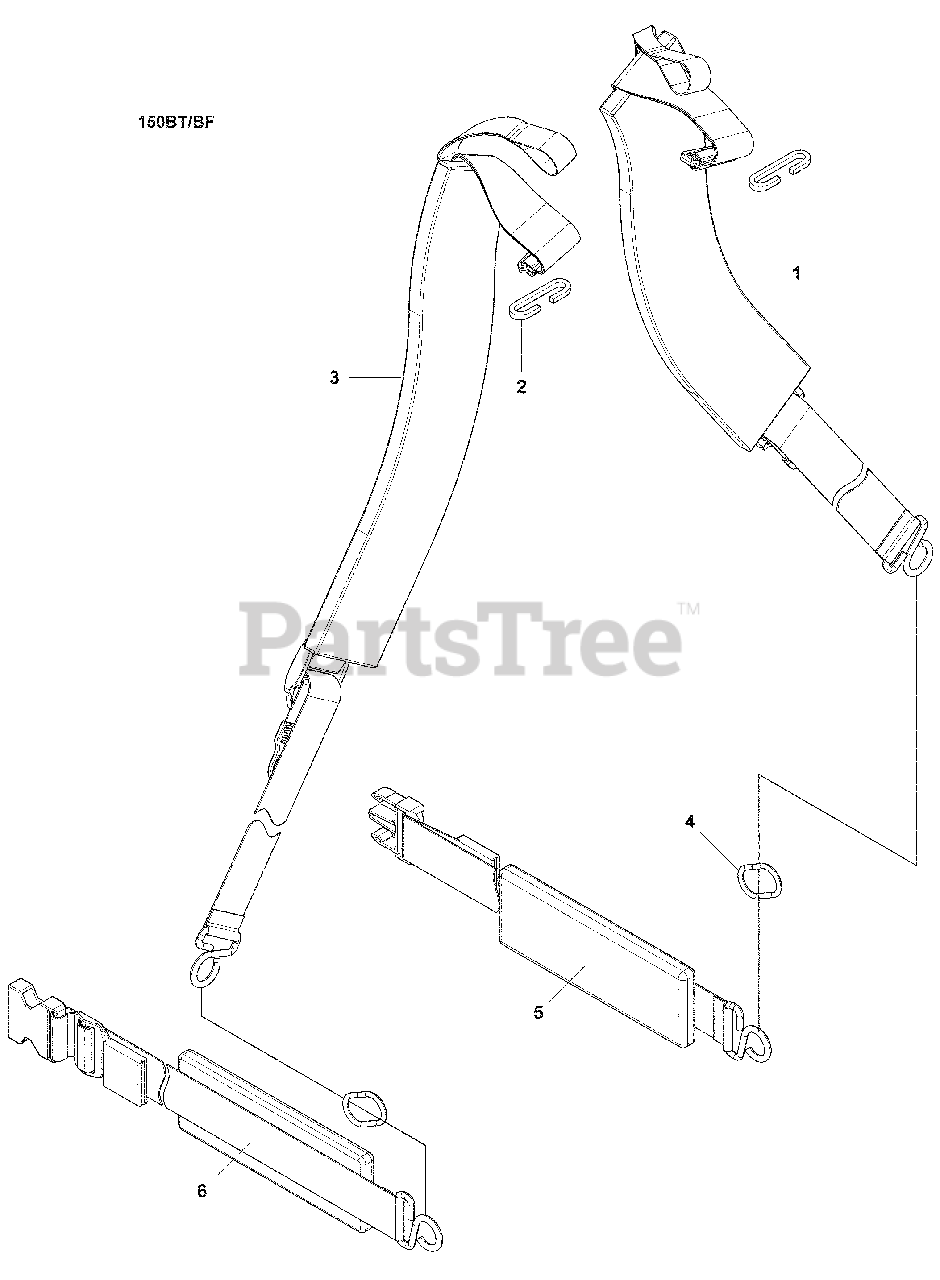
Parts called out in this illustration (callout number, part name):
1	Shoulder Strap, RH
3	Shoulder Strap, LH
4	Ring
5	Shoulder Strap, RH
6	Shoulder Strap, LH
